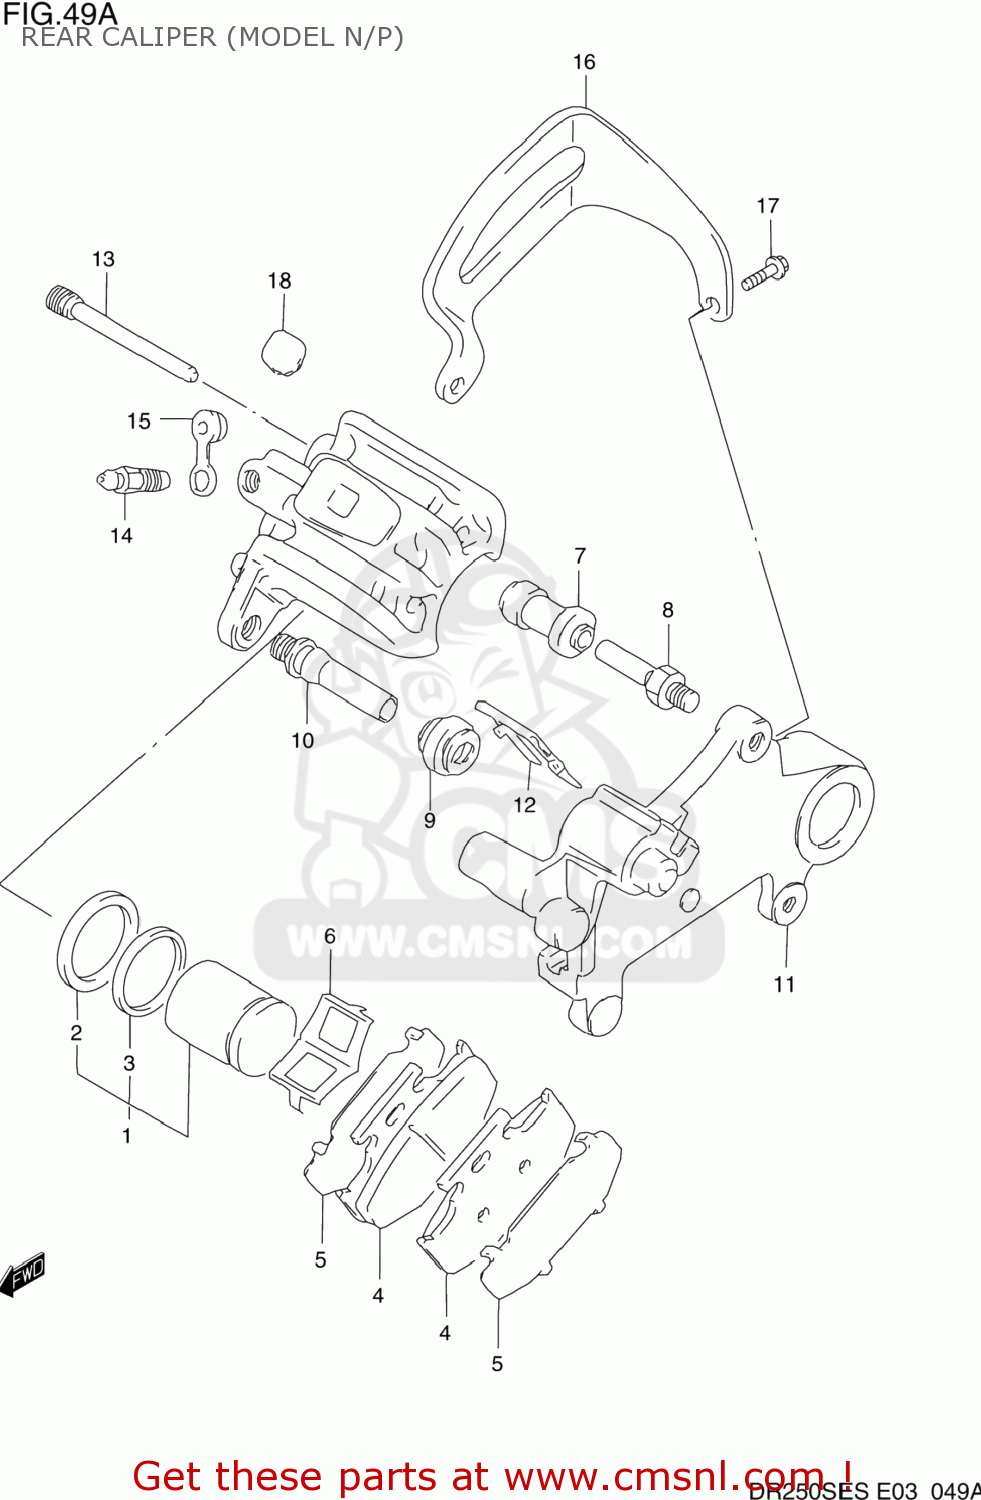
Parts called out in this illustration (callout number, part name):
1	PISTON SET
2	SEAL,PISTON
3	SEAL
4	PAD (MCA)
5	SHIM
6	SPRING,PAD
7	BOOT
8	PIN,BOLT
9	BOOT
10	PIN
11	BRACKET
12	RETAINER,BRACKET
13	PIN,HANGER
14	BLEEDER
15	CAP,BLEEDER
16	GUARD,RR CALIPER
17	BOLT
18	COVER,RR CALIPER BODY
